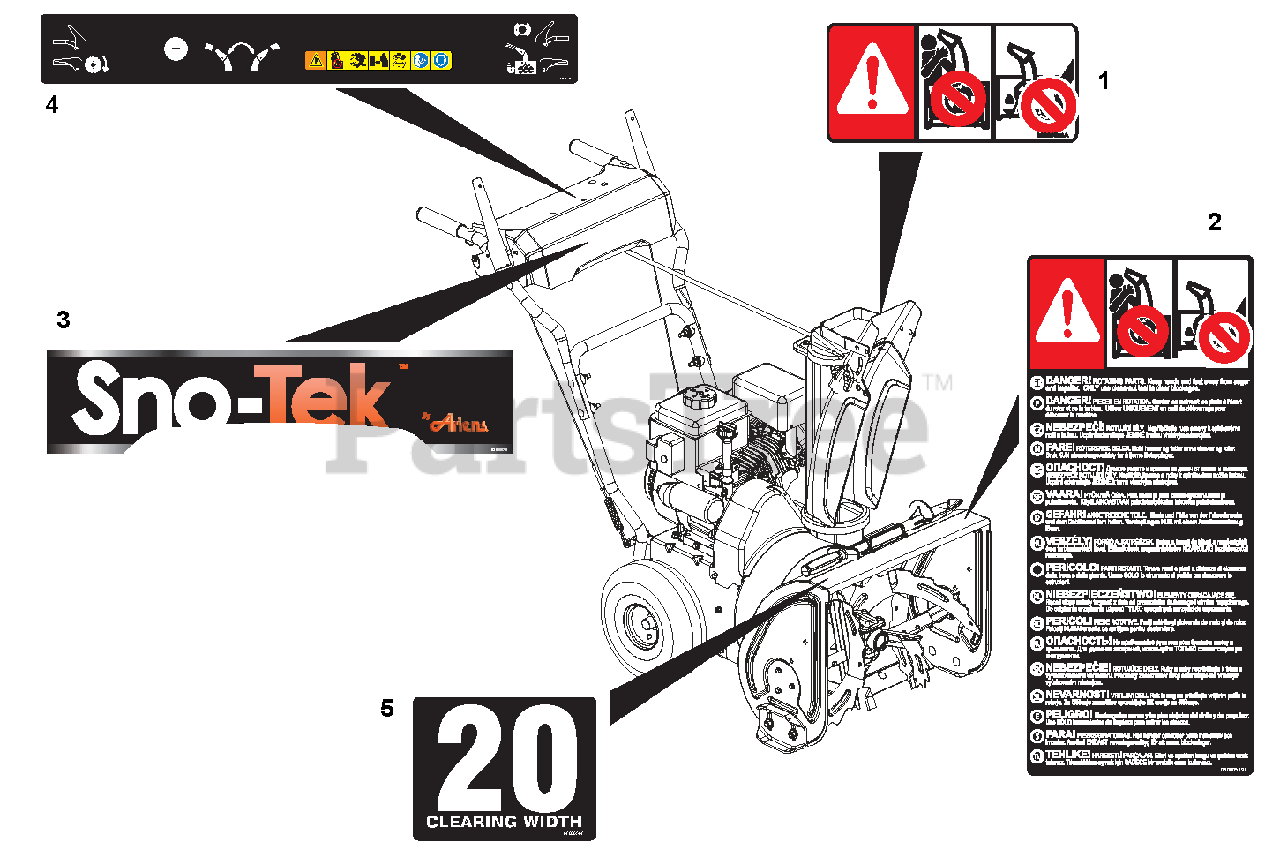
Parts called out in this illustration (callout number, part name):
1	DECAL, DANGER
2	DECAL, DANGER - ROTATING PARTS
3	DECAL, DASH - SNO-TEK
4	DECAL, CONTROL - SINGLE SPEED
5	DECAL, HOUSING SNO-TEK 20
